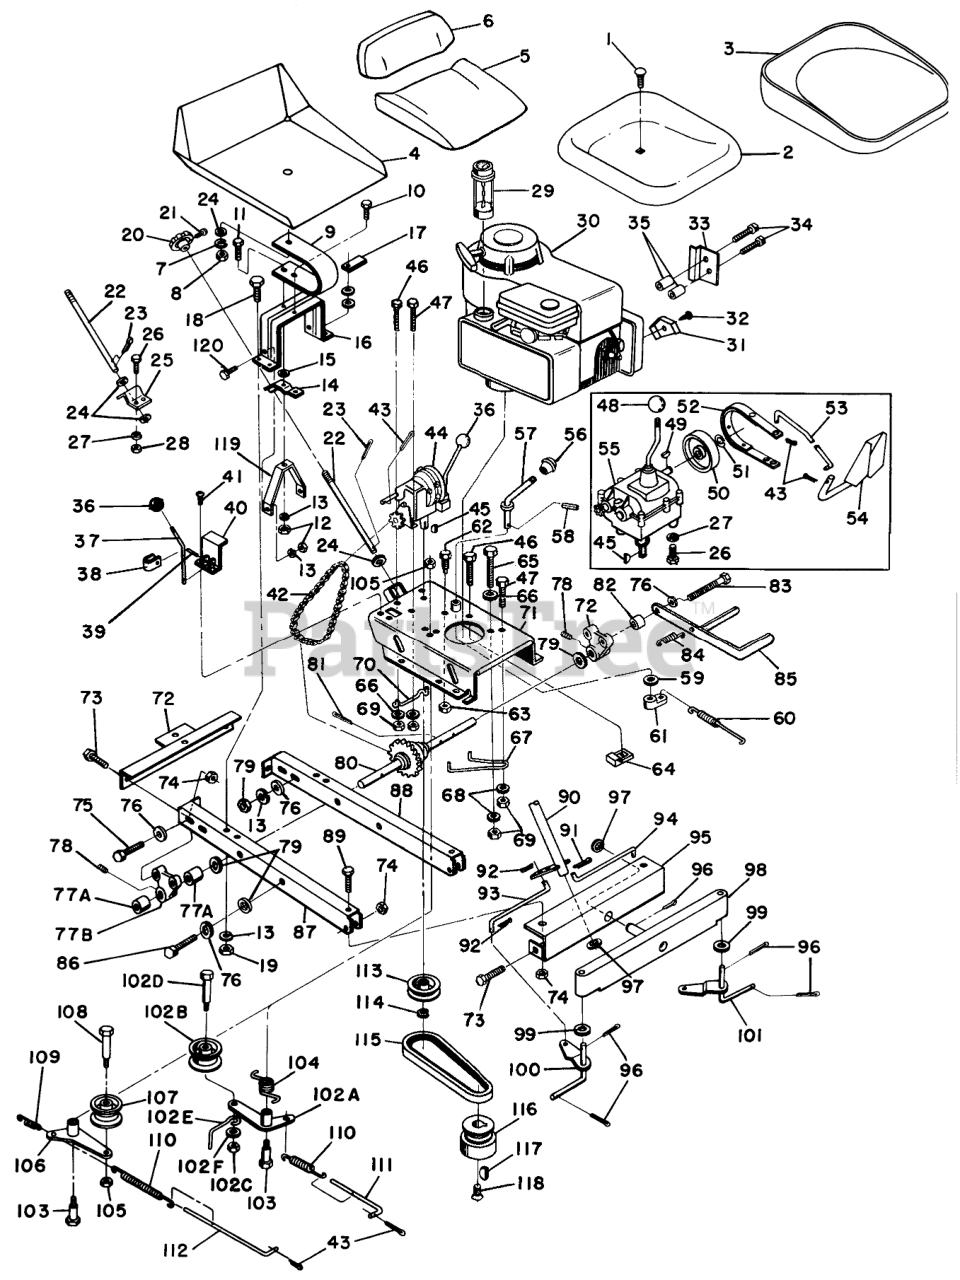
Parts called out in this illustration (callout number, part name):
1	SCREW-CARR
2	Frame, Seat
3	Cushion, Seat
4	Frame, Seat
5	Cushion, Seat
6	Cushion Back
7	WASHER-LOCK
8	NUT-JAM
9	Spring, Seat
10	SCREW-HH
11	SCREW-HH
12	NUT-HEX
13	WASHER-LOCK
14	Adjustment Strap
15	WASHER-FLAT
16	Support, Seat
17	Stop, Brake
18	SCREW-HH
19	NUT-HEX
20	Handle, Height Adjustment
22	Screw, Height Adjustment
23	PIN-ROLL, SLOTTED
24	WASHER-FLAT
25	Bracket, Adjustment
26	SCREW-HH
27	WASHER-LOCK
28	NUT-JAM
29	Gas Gage
30	Engine
31	Deflector, Exhaust
32	Screw (Supplied with Engine)
33	Baffle
34	SCREW-HH
35	Spacer
37	Shift Lever
38	Clip, Shift Lever
39	Rollpin
40	Shield, Chain
42	Chain, Drive
43	PIN-COTTER
44	Transmission Assy
45	KEY-WOODRUFF
46	SCREW-HH
47	SCREW-HH
48	KNOB-CONTROL
49	KEY-WOODRUFF
50	Drum, Brake
51	E-RING
52	Brake Band Assy
53	Rod, Brake
54	Brake Pedal
55	Transmission Assy
57	Blade Rod Assy
58	PIN-SPRING
59	WASHER-SPRING
60	Spring, Blade Control
61	Blade Lever
62	SCREW-HH
63	NUT-JAM
64	Nut, Retainer
65	SCREW-HH
66	WASHER-FLAT
67	Belt Guard
67	Belt Guide
68	Flat Washer
69	Nut
70	Belt Guide
71	Engine Mounting Plate Assy
72	Frame, Rear
73	SCREW-HH
75	SCREW-HH
76	WASHER-FLAT
77	Support Assy, Rear Axle
77A	BUSHING
77B	Support, Rear Axle
78	Zerk Fitting
79	Washer
80	Differential (with Rear Axle)
81	PIN-COTTER
82	Pivot, Brake
83	SCREW-HH
84	Centering Spring
85	Foot Brake
86	Sems Screw
87	Frame Assy, R.H.
88	Frame Assy, L.H.
89	SCREW-HH
90	Steering Shaft Assy
91	PIN-COTTER
92	PIN-COTTER
93	Tie Rod, R.H.
94	Tie Rod, L.H.
95	Frame, Front
96	PIN-COTTER
97	WASHER-FLAT
98	Front Axle
99	Washer
100	Spindle, R.H.
101	Spindle, L.H.
102	Idler Arm Assy
102A	Idler Arm
102B	Pulley
102D	SCREW-HH
102E	Belt Retainer
102F	WASHER-FLAT
103	Shoulder Bolt
104	Spring, Torsion
106	Idler Arm Assy
107	Pulley
108	SCREW-HH
109	Spring, Clutch Return
110	Spring
111	Rod, Clutch
112	Rod, Clutch
113	Pulley, Transmission
114	RING-SNAP, EXTERNAL
115	V-Belt
116	Cup, Clutch
117	KEY-WOODRUFF
118	Screw, Clutch
119	Brace, Seat Support
120	SCREW-HH
